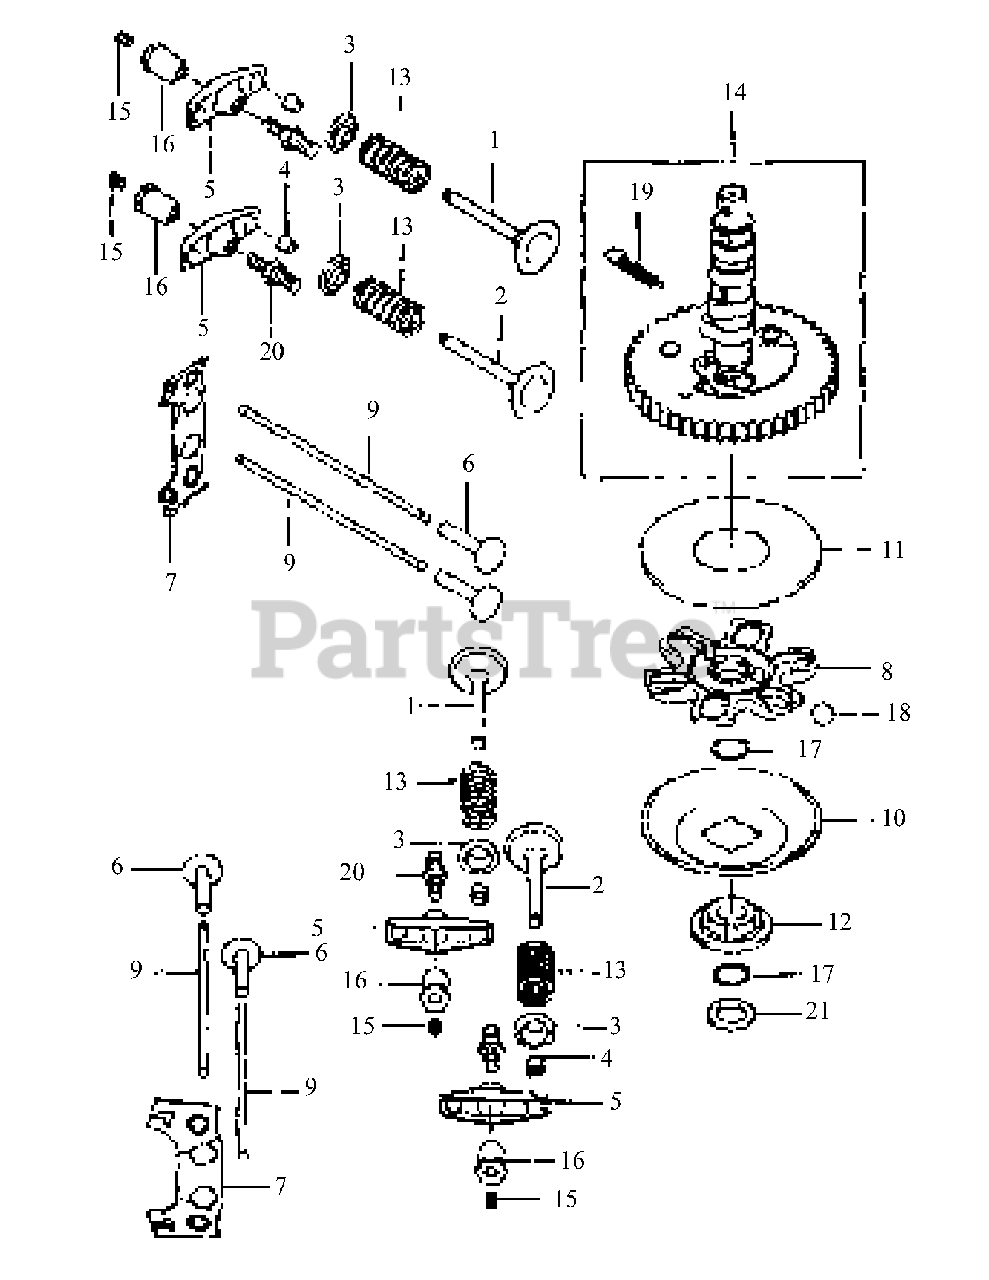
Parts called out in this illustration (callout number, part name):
1	Valve, Intake
2	Valve, Exhaust
3	Retainer, Valve Spring
13	Spring, Engine Valve
14	Camshaft, Comp.
17	Ring, Snap
18	Ball
19	Spring
